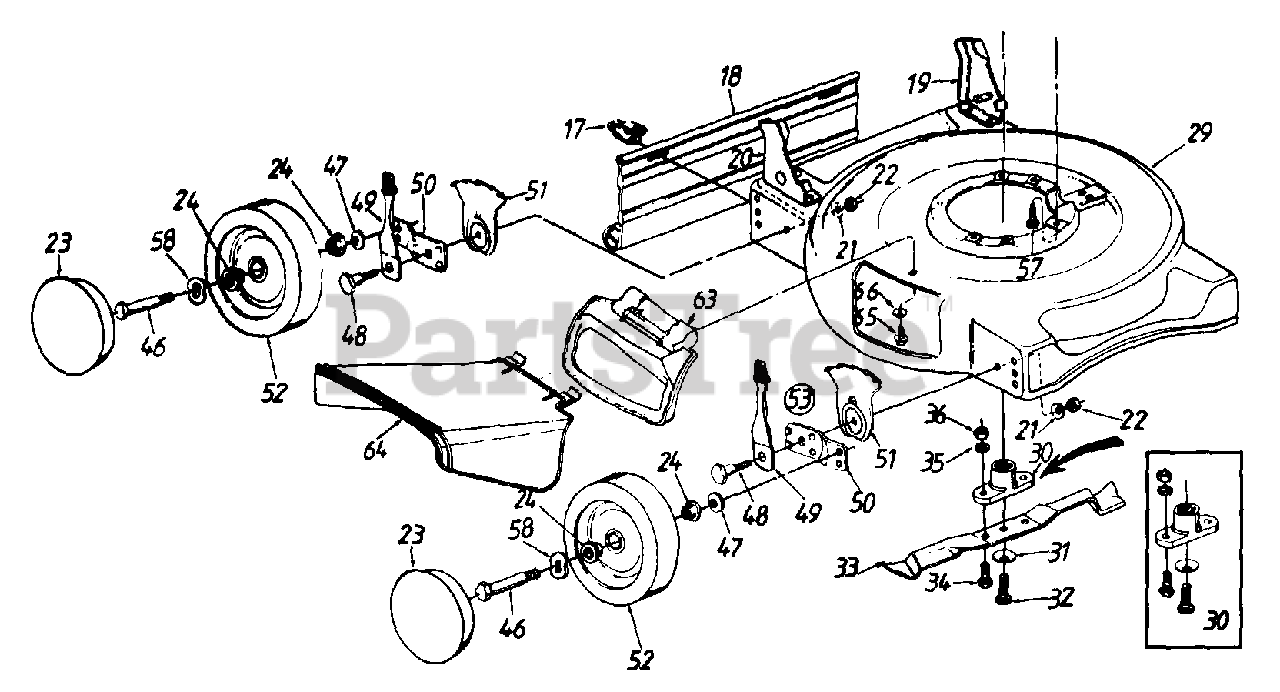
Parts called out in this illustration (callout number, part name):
17	Hinge Clip
18	Rear Flap (106F)
22	Hex Nut 3/8-16 Thd.
23	Hub Cap
24	Bearing
29	20" Deck Ass'y. (106F)
30	Blade Adapter Kit
31	Bell-Wash. .46" I.D.
32	Hex Bolt 7/16-20 x 1.5" Lg.
33	20" Mulching Blade (106F)
34	Hex Bolt 3/8-24 x 1" Lg.
35	L-Wash. 3/8" I.D.
36	Hex Nut 3/8-24 Thd.
47	Bell-Wash. .400" I.D. x .88"
48	Shld. Bolt .50" Dia. x .357"
49	Spring Lever Ass'y. w/Knob
51	Height Adj. Plate
52	Wheel Ass'y. Comp.
53	Height Adj. Ass'y. Comp. - R.F. & L.R.
57	Hex L-Wash. Hd. Scr. 3/8-16 x 1.0" Lg.
58	Wave Washer .51" I.D.
63	Mulching Plug (106F)
64	Chute Deflector
65	Bell-Wash. 1/4" I.D.
66	Hex Wash. Hd. TT-Tap Scr. 1/4-20 x .5" Lg.
